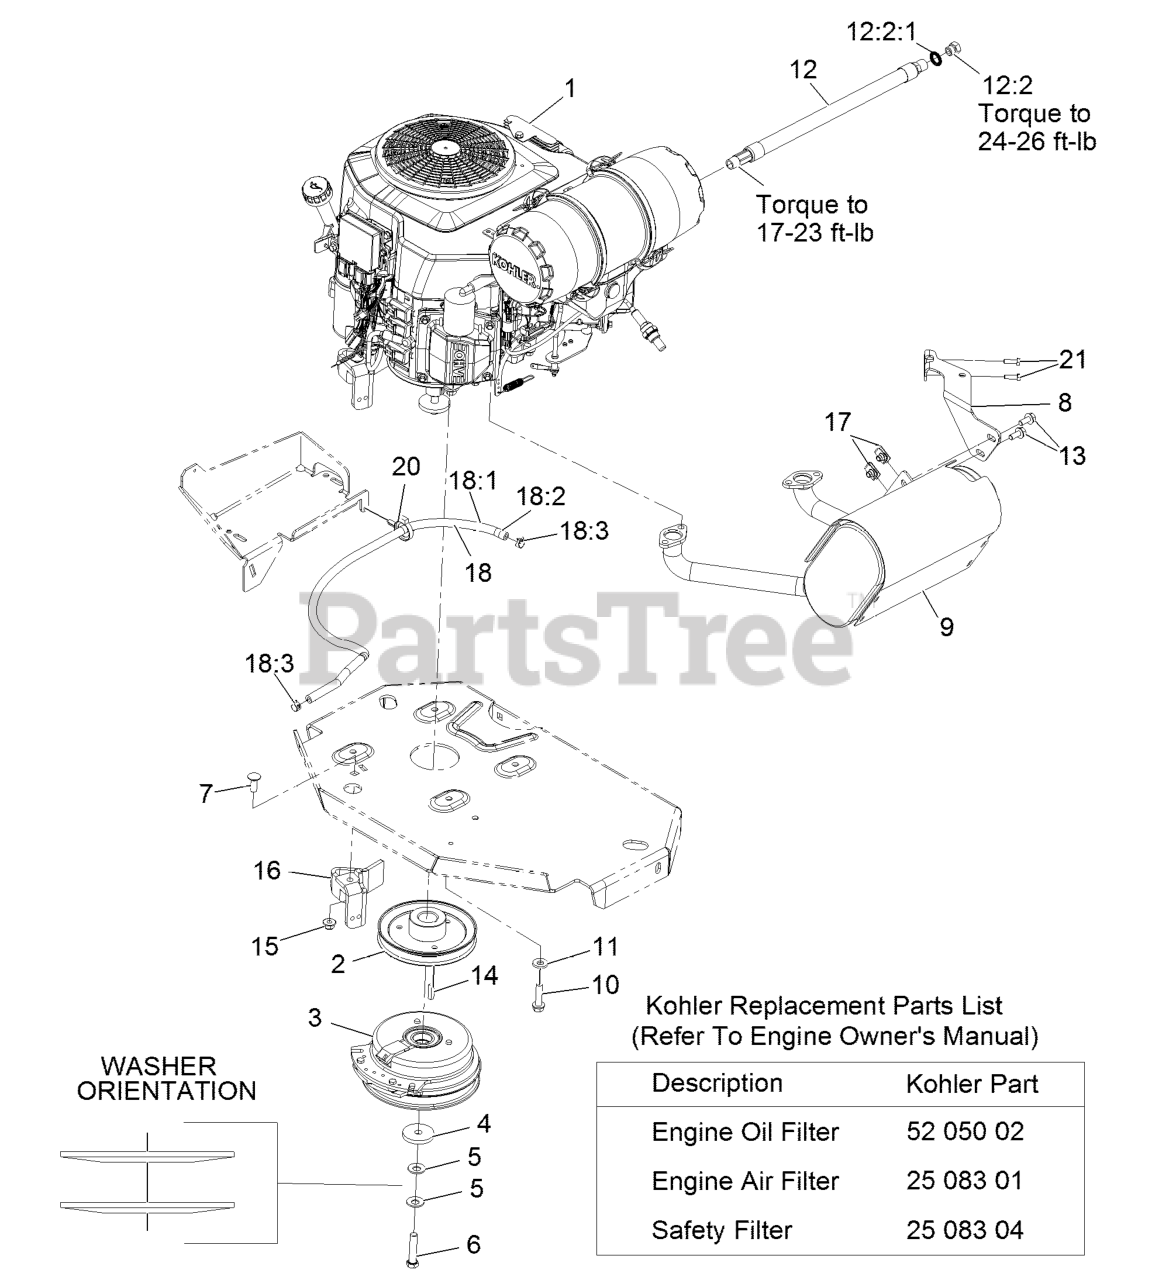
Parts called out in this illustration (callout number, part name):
1	Engine-Kohler
2	SHEAVE
3	CLUTCH KIT
4	WASHER-CLUTCH
5	WASHER-SPRING
6	SCREW-HH W/LOCTITE
7	SCREW-CARR
8	MUFFLER BRACKET KIT
10	SCREW-HWH
11	WASHER-BELLEVILLE
12	OIL DRAIN HOSE ASM
12:2	PLUG-HH
12:2:1	O-RING
13	SCREW-HHF
15	NUT-HF, NI
16	CLUTCH-ANCHOR
18	FUEL LINE ASM
18:1	HOSE-FUEL
18:2	SLEEVE-THERMAL
18:3	CLAMP-HOSE
20	CLAMP-HOSE
21	SCREW-HH M6-1 X 20Mm W/Patch
